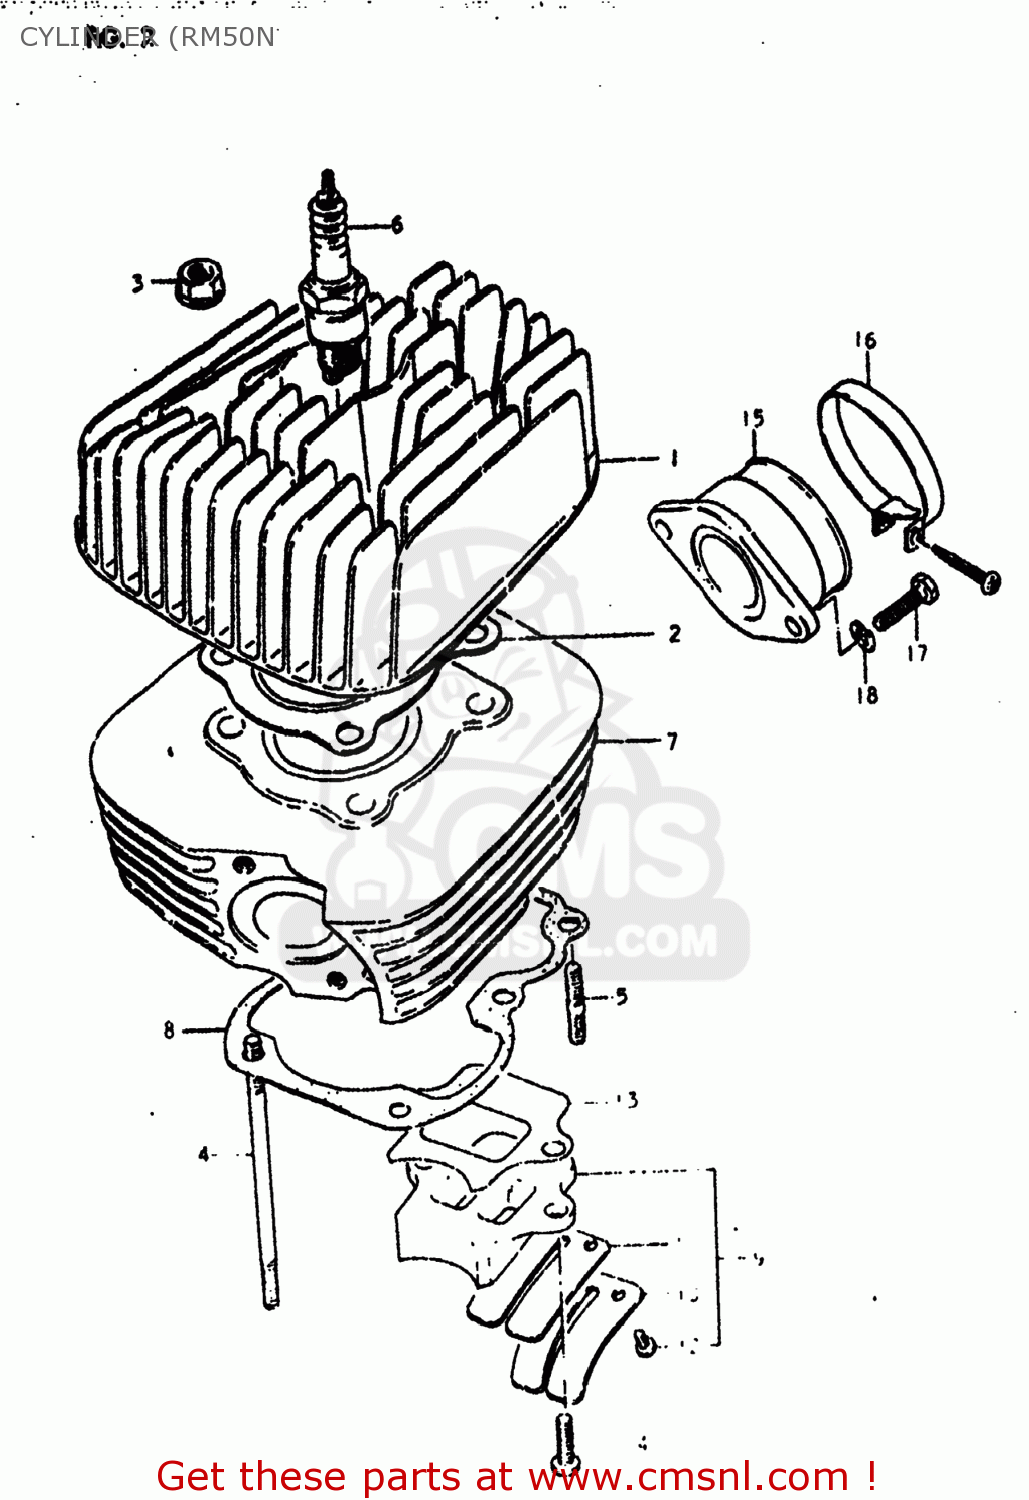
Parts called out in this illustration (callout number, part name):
1	HEAD,CYLINDER
2	GASKET,CYLINDER HEAD (NAS)
3	NUT
4	STUD BOLT
5	STUD BOLT
6	PLUG,SPARK(B7HS)
7	CYLINDER
8	GASKET,CYLINDER
9	VALVE ASSY,REED
10	STOPPER,REED VALVE
11	VALVE,REED
12	SCREW,REED VALVE
13	GASKET,REED VALVE (MCA)
14	SCREW
15	PIPE,INTAKE
16	CLAMP
17	BOLT, UPPER
18	LOCK WASHER
